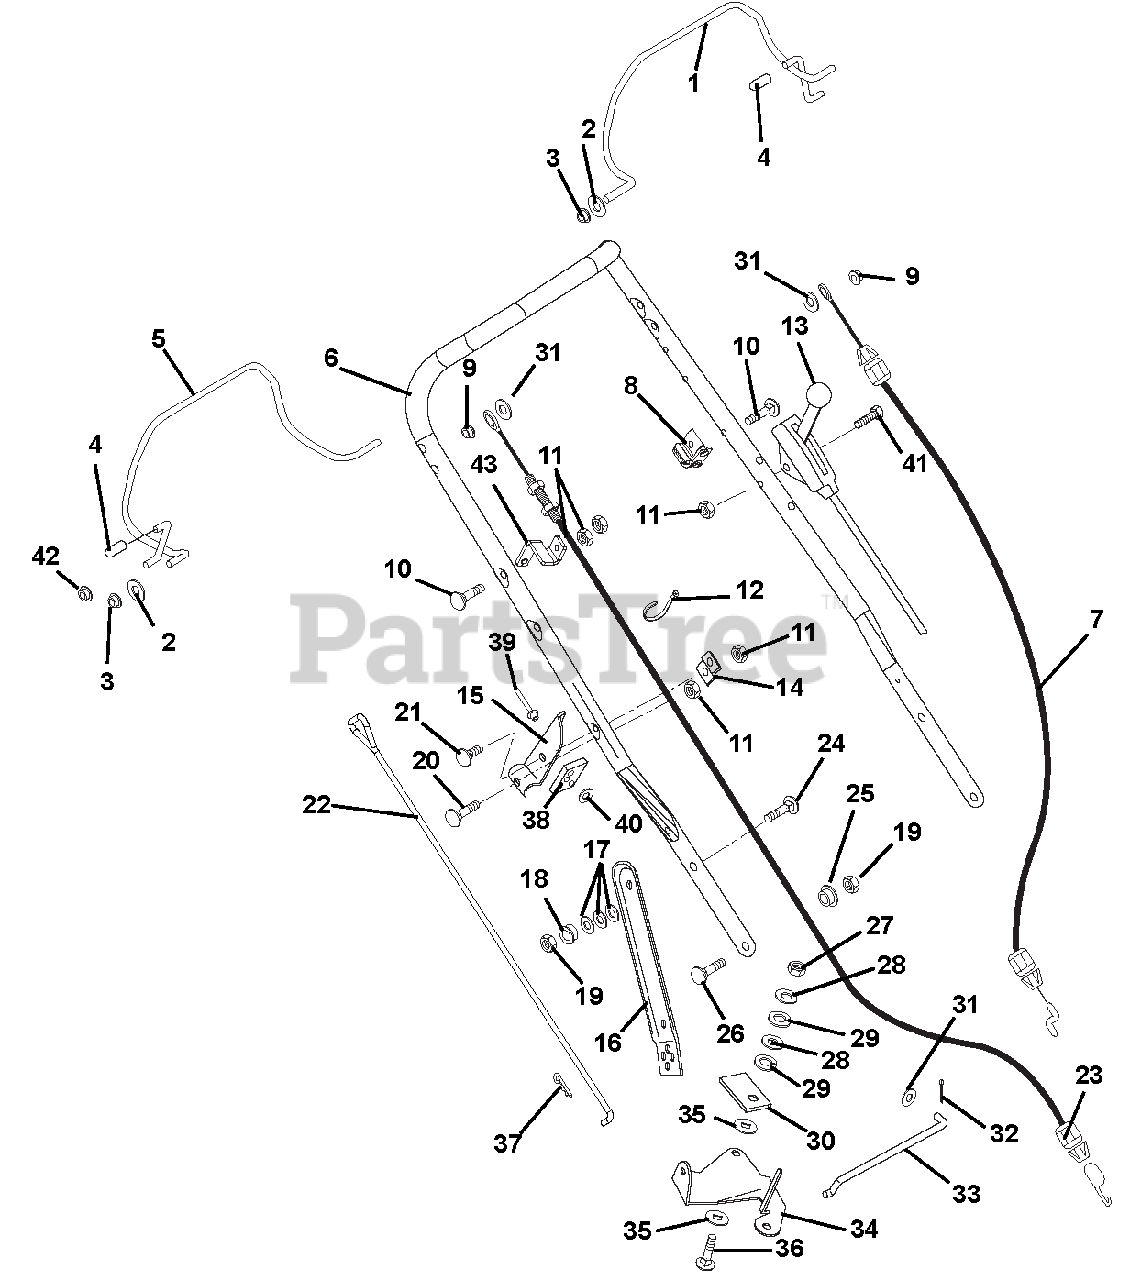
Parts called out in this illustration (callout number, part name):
1	BAIL, WBLM ENGINE
2	@WSHR-FL-STL.344X.688X.065YWZC
3	BSHG-FLG .325X.444X.440X.560
4	CAP, VINYL, .25 ID
5	BAIL, WBLM TRACTION
6	HANDLE BAR, CLASSIC LM21
7	CABLE, WBLM ENGINE
7	CABLE, ENGINE - ADJUSTABLE
8	ANCHOR, WBLM ENGINE CABLE
9	PUSH NUT, .25
10	BLT-RDHDXLSQNK.25-20X1.25 G5ZC
11	@NUT-LK-CTR .25-20 YWZC
12	CABLE TIE LG 5-1/2
13	CABLE, LOCKOUT CONTROL
14	BRACE, SPEED CONTROL
15	BRACKET, SPEED CONTROL
16	LINK, HANDLEBAR ADJUSTMENT LH
16	LINK, HANDLEBAR ADJUSTMENT RH
17	WASHER, BELLEVILLE YWZC
18	BSHG-FLG .325X.500X.513X.875
19	@NUT-LK-CTR .31-18 YWZC
20	@BLT-RDHDSQNK .25-20X1.50 G5YZ
21	@BLT-RDHDSQNK .25-20X.50 G5YZ
22	ROD, SPEED CONTROL
23	CABLE, WBLM TRACTION
24	@BLT-RDHDSQNK .31-18X1.00 G5YZ
25	BSHG, FLG .325X.499X.26X.88
26	@BLT-RDHDSQNK .31-18X.75 G5YZ
27	@NUT-LK-CTR .38-16 YWZC
28	@WSHR-FL-STL.406X.812X.065 YWZ
29	WSHR-LK .375X.115 HVY YWZC
30	PRESSURE FLANGE
31	@WSHR-FL-STL.281X.62X.065 YWZC
32	@PIN-CTR .06X.50 EXTPRSQCT YWZ
33	SHIFT LINK
34	BELL CRANK - SPEED CONTROL
35	FRICTION WASHER
36	@BLT-RHDSSQNK .38-16X1.25 G5YZ
37	PIN-HAIR INT .08X.18X1.18 YWZC
38	SUPPORT PAD
39	RVT .187X.575 DOME AL BLACK
40	@WSHR-FL-STL.219X.50X.049 YWZC
41	BLT-RDHDXLSQNK .25-20X2.0 G5YZ
42	NUT-PUSH .312 DIA. PAL
43	BRKT, TRACTION CABLE ANCHOR
